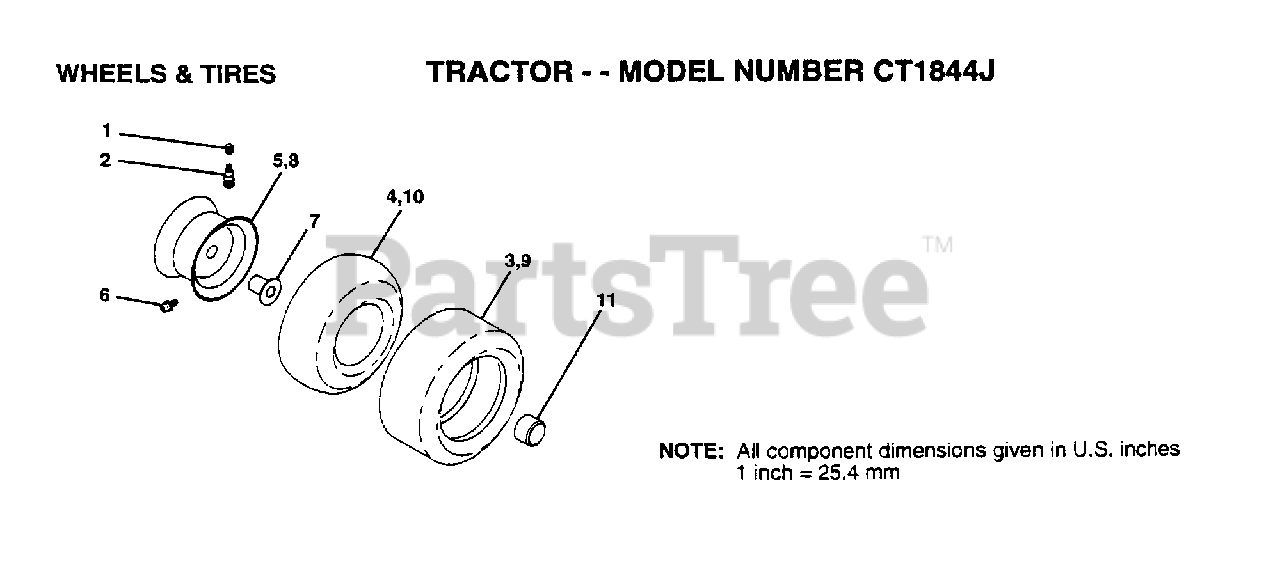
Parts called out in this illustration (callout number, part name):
1	VALVE CAP
2	VALVE STEM LT
4	TUBE.5.3/4.5/6
5	"RIM.FRONT.8"".YEL"
6	FITTING LT
7	"FLANGE, BEARING"
8	"RIM.REAR.12"".LT"
10	TUBE.23X8/10-12
11	HUB CAP
